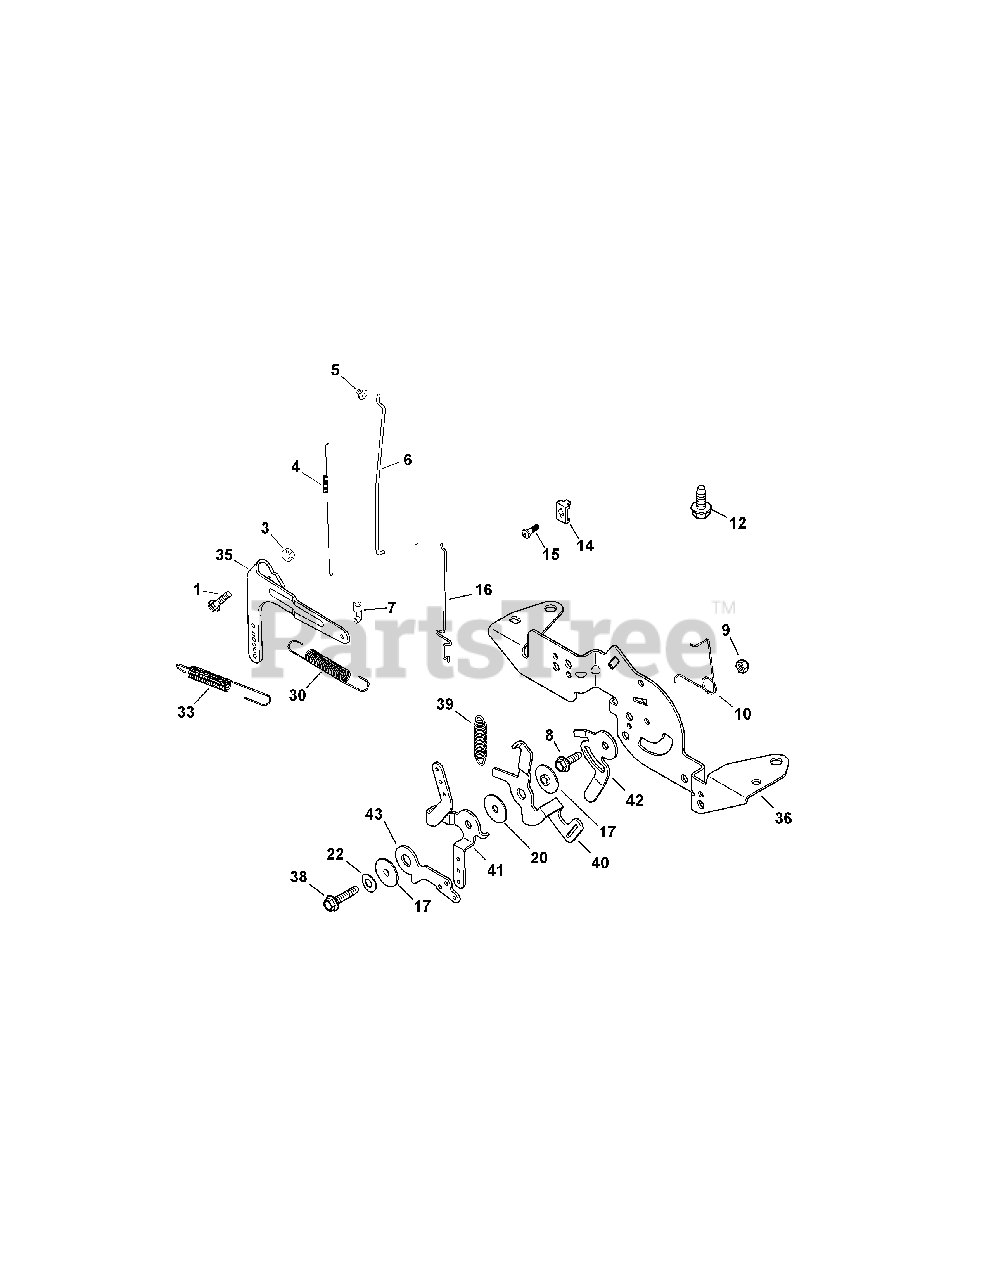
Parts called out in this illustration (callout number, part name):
1	Rd. Hd. Sq. Neck Bolt, M6 x 1.0 x 25
3	Flg. Nut, M6 x 1.0
4	Linkage Spring
5	Linkage Retaining Bushing
6	Throttle Linkage
7	Throttle Linkage Bushing
8	Flg. Thd. Frm. Screw, M5 x 0.8 x 16
9	Lock Nut, M5 x .8
10	Choke Return Spring
12	Flg. Thd. Frm. Screw, M6 x 1.0 x 16
14	Cable Clamp
15	Lbd. Thd. Frm. Screw, M5 x 0.8 x 16
16	Choke Linkage
17	Control Assembly Spacer
20	Flat Washer, 5.5mm
22	Spring Washer, 1/4
30	Governor Spring
33	Governor Spring
35	Governor Lever
36	Control Bracket
38	Thd. Frm. Screw, M5 x 0.8 x 25mm
39	Speed Control Spring
40	Governor Spring Lever
41	Speed Control lever
42	Speed Setting lever
